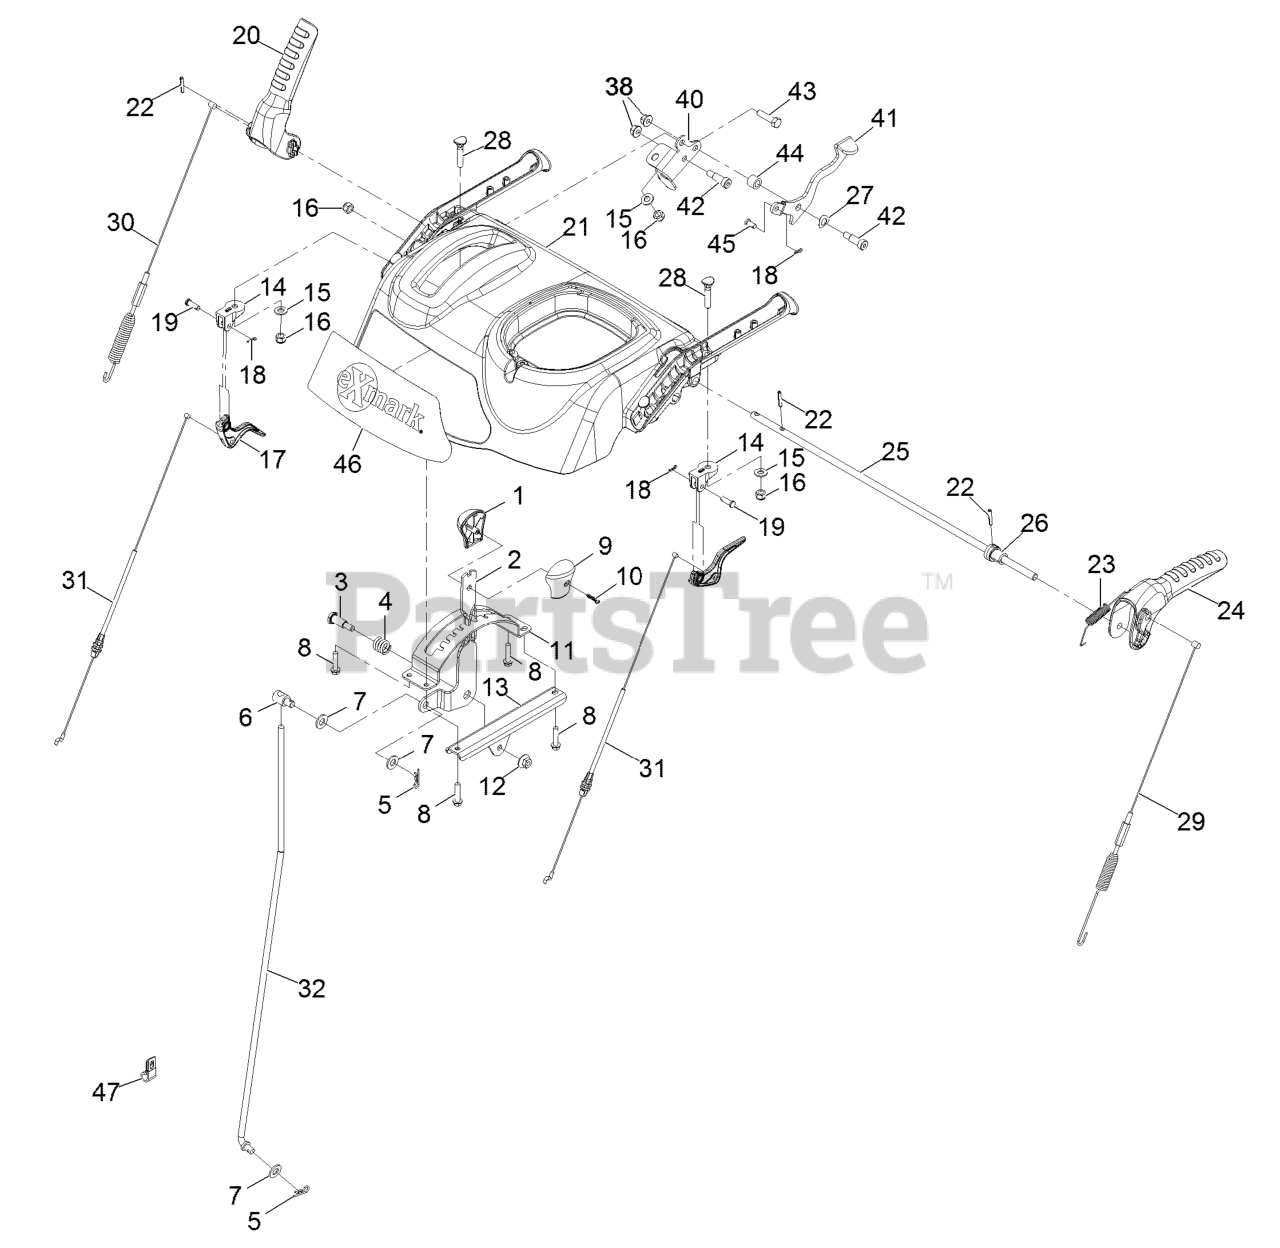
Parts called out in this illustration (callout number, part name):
1	KNOB-SHIFT, RH
2	SELECTOR-SPEED
3	SCREW-SHOULDER
6	TRUNNION-ROD
7	WASHER-FLAT
8	SCREW-PLASTITE
9	KNOB-SHIFT, LH
10	SCREW-PPH
11	GUIDE-SELECTOR, SPEED
13	MOUNT-SELECTOR, SPEED
14	MOUNT-LEVER, CLUTCH
15	WASHER-FLAT
16	NUT-LOCK, NI
17	LEVER-CLUTCH
18	PIN-HAIR
19	PIN-CLEVIS
20	LEVER-AUGER
21	PANEL, CONTROL W/DECAL CE
22	PIN-SPRING
23	SPRING-TENSION
24	LEVER-TRACTION
25	ROD-LOCKOUT
26	CAM-LOCKOUT
27	WASHER-SPRING
28	SCREW-HANDLE
29	CABLE-TRACTION
30	CABLE-AUGER
31	CABLE-CLUTCH
38	NUT-HF, NI
40	BRACKET-LEVER, BROOM ANGL
41	LEVER-THUMB, BROOM ANGLE
42	SCREW-SHOULDER, HSH
43	SCREW-HH
44	TUBE-SPACER
45	PIN-CLEVIS
46	DECAL-EXMARK LOGO
47	CLIP-LOOM
